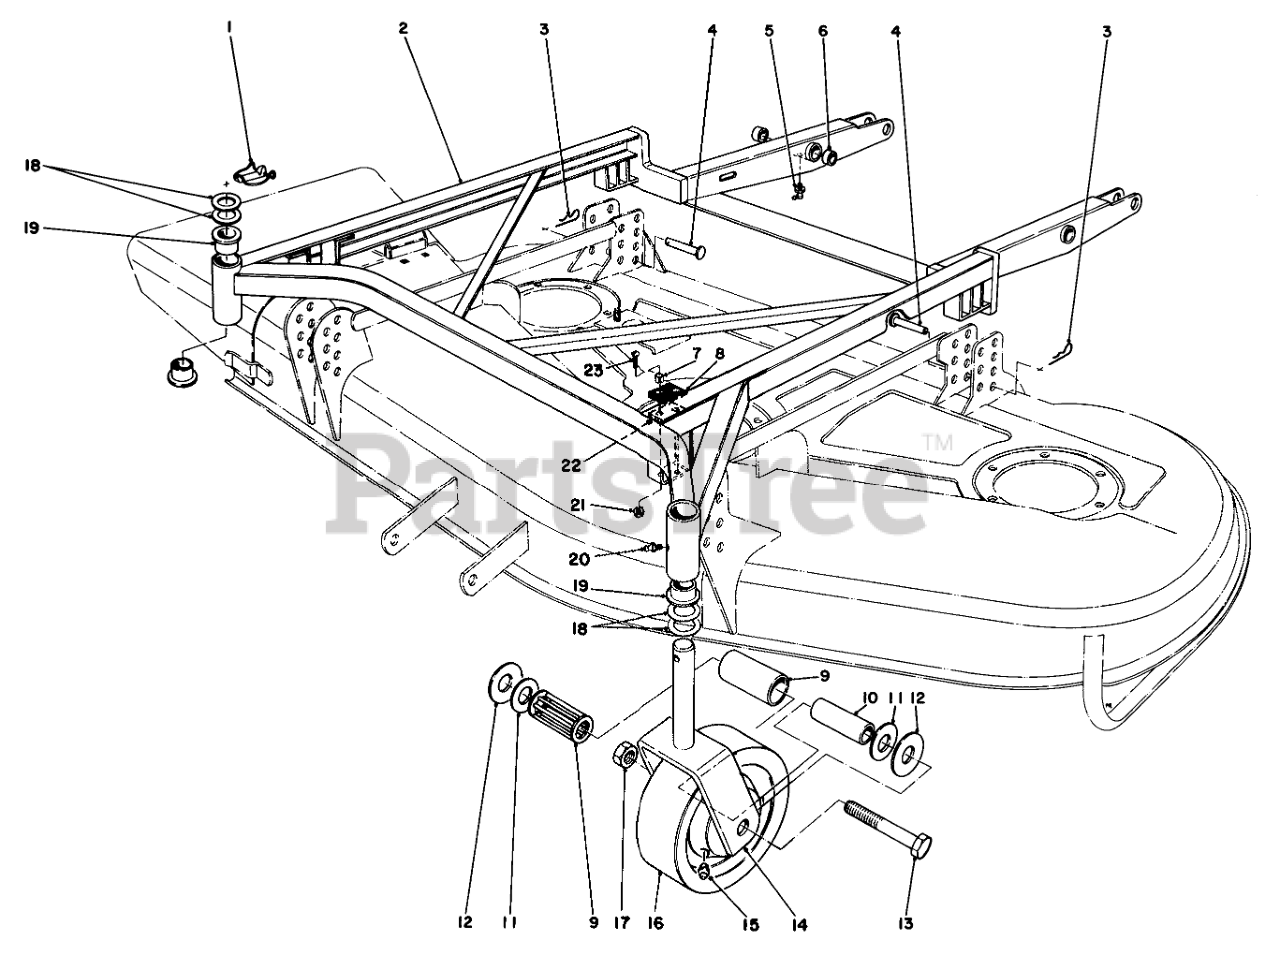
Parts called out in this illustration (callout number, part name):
1	PIN-LYNCH
2	Frame-Deck Suspension (Incl. Ref. #5-6 & 19)
3	PIN-HAIR
4	PIN-CLEVIS
5	FITTING-GREASE, 90 DEG
6	7/8 ID X 1.128 X 7/8 LG BSHG
7	SPACER
8	CUSHION-RUBBER
9	ROLLER BEARING
10	SPANNER BUSHING
11	BEARING RETAINER
12	THRUST WASHER
13	SCREW-HH
14	FORK-Castor
15	FITTING-GREASE
16	Wheel Assy. (Incl. Ref. #9-12 & 15)
17	NUT-LOCK
18	WASHER-THRUST
19	Bushing
20	FITTING-GREASE
21	NUT-LOCK, NI
22	SHIM-CUSHION
